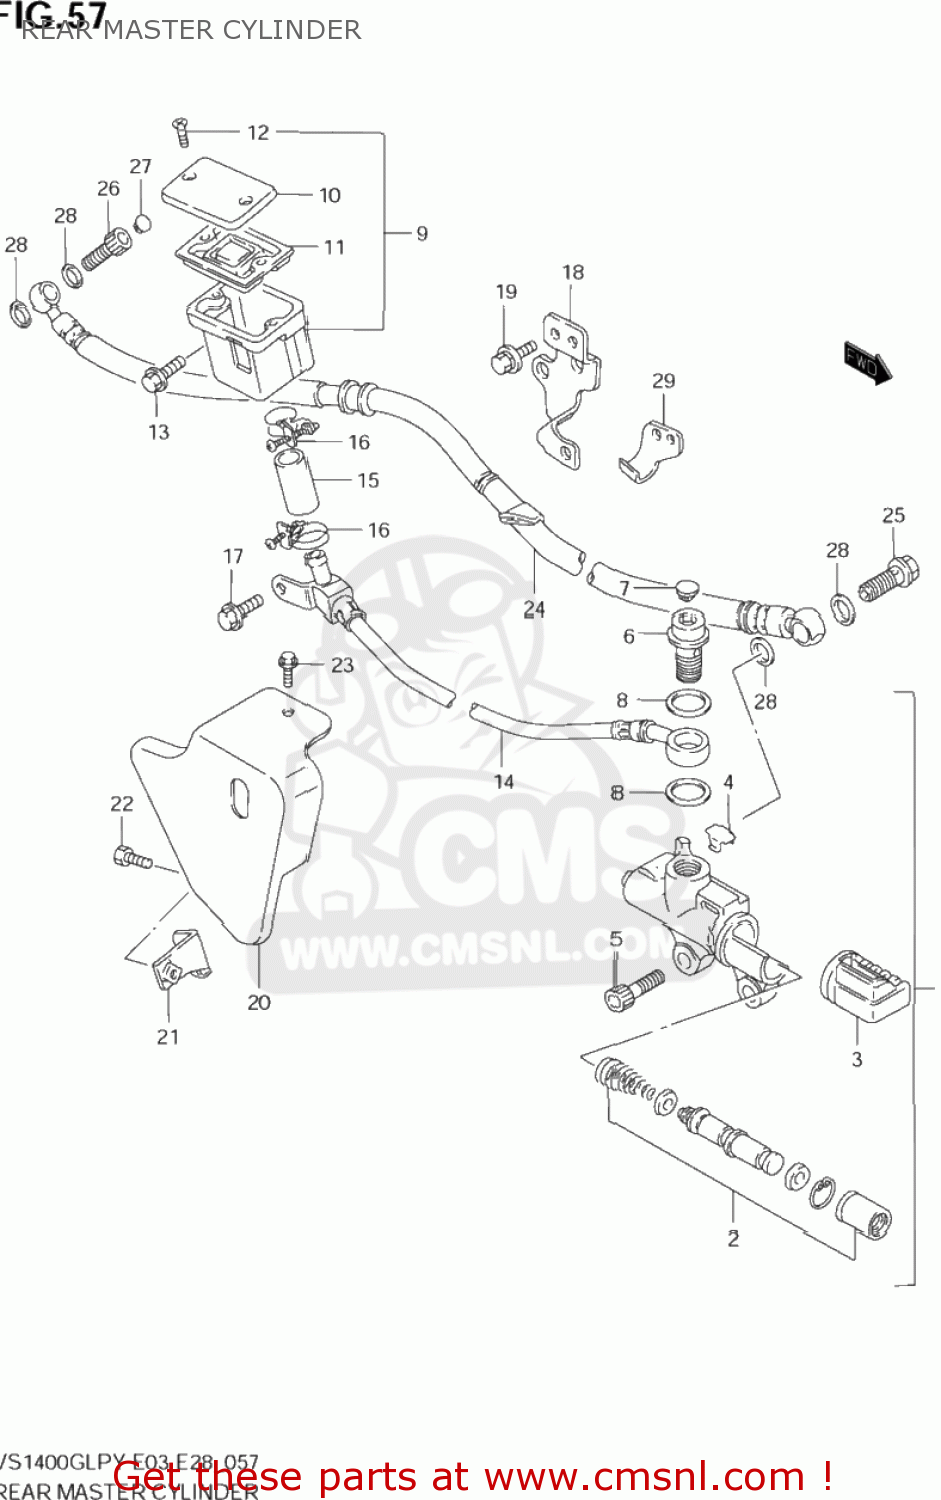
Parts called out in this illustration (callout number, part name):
1	CYLINDER ASSY,RR MASTER
2	PISTON/CUP SET
3	BOOT
4	PLATE,STOP
5	BOLT(8X30)
6	BOLT UNION
7	CAP(OD:12)
8	WASHER,BRAKE FLUID
9	TANK ASSY,RESERVOIR
10	CAP
11	DIAPHRAGM
12	SCREW
13	BOLT
14	HOSE,RESERVOIR TANK
15	HOSE,RESERVOIR TANK
16	CLIP
17	BOLT
18	BRACKET,RESERVOIR TANK
19	BOLT
20	COVER,RESERVOIR TANK
21	BRACKET COMP,RESERVOIR TANK
22	SCREW(6X10)
23	BOLT
24	HOSE,REAR BRAKE
25	BOLT UNION
26	BOLT UNION
27	CAP(OD:12)
28	WASHER(10X15X1.5)
29	CLAMP,RR BRAKE HOSE
